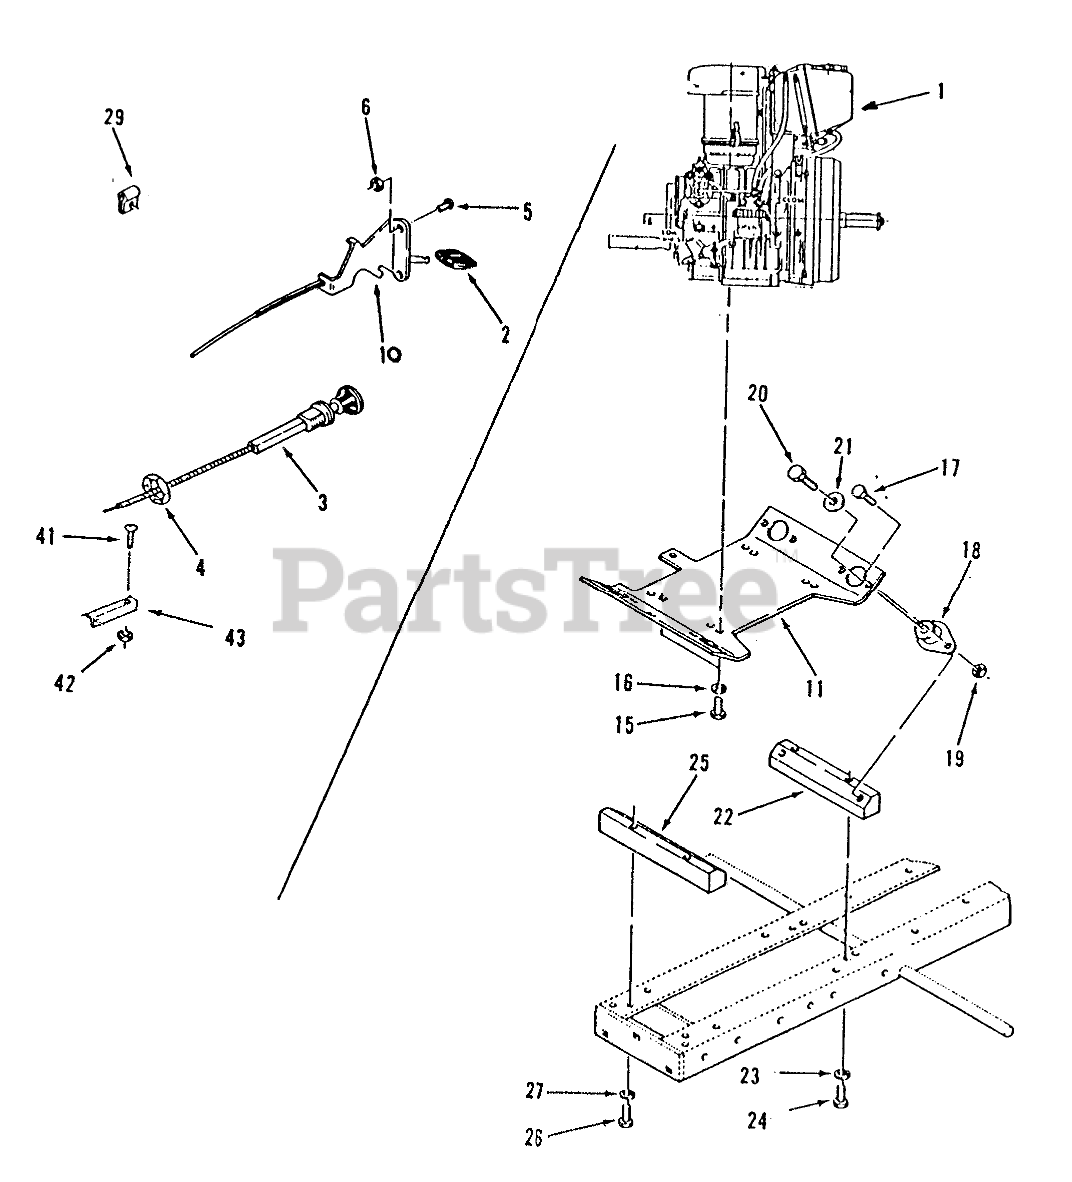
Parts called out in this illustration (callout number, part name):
1	Diesel Engine Robin DY 41D
2	KNOB-THROTTLE
3	CONTROL-STOP
4	NUT-HEX PALNUT
5	Screw
6	Nut
10	Throttle Control
11	PLATE ENGINE B
15	Bolt 3/8-16 x 2 1/2
16	Washer
17	H H C S
18	MOUNT-ISOLATION
19	Nut
20	Bolt
21	Washer
22	MOUNT BLOCK-REAR
23	LOCKWASHER
24	Bolt
25	MOUNT BLOCK-REAR
26	BOLT
27	LOCKWASHER
29	CLIP-CABLE
41	Pan HD. Cross Rec. Machine Screw #4-40 x 3/8
42	NUT HEX 4-40 ELAST
43	BRACKET-ENGINE STOP
